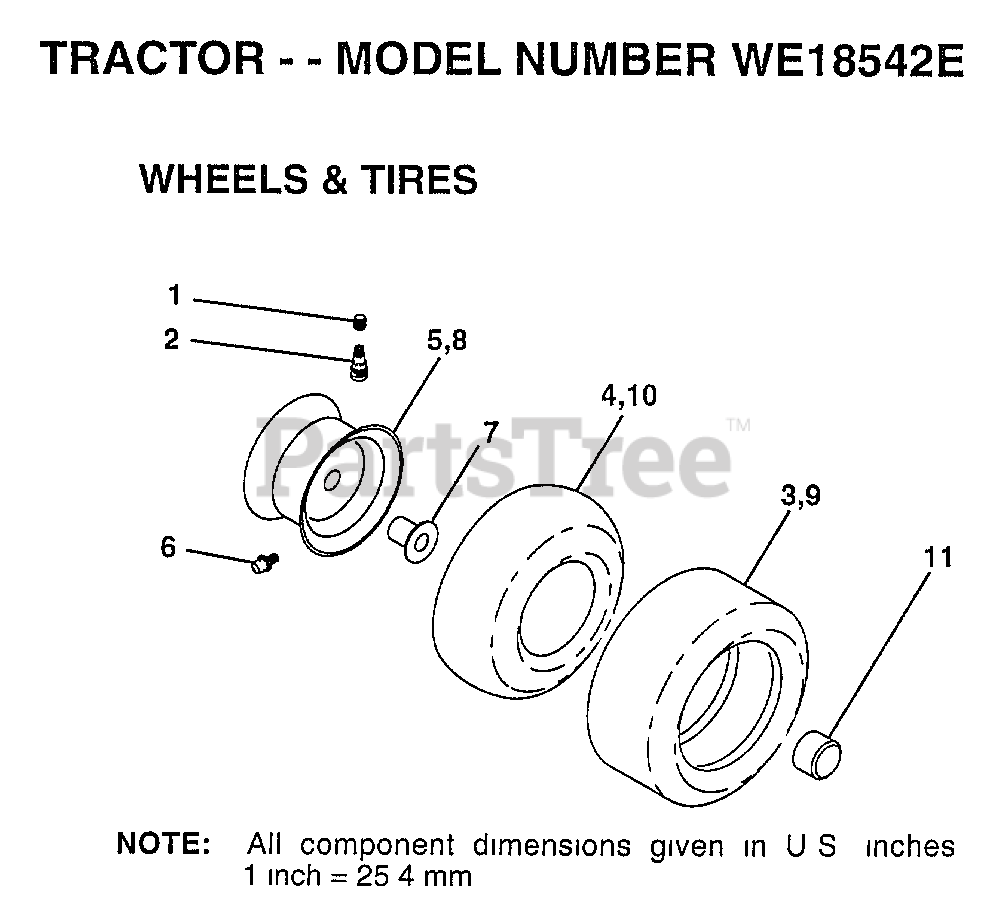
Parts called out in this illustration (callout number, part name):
1	VALVE CAP
2	VALVE STEM LT
4	TUBE.5.3/4.5/6
5	"RIM ASM 6"" FRT"
6	FITTING LT
7	"FLANGE, BEARING"
8	"RIM AS 8"" REAR"
9	TIRE.20X8-8
10	TUBE.18X9.5-8
11	HUB CAP
